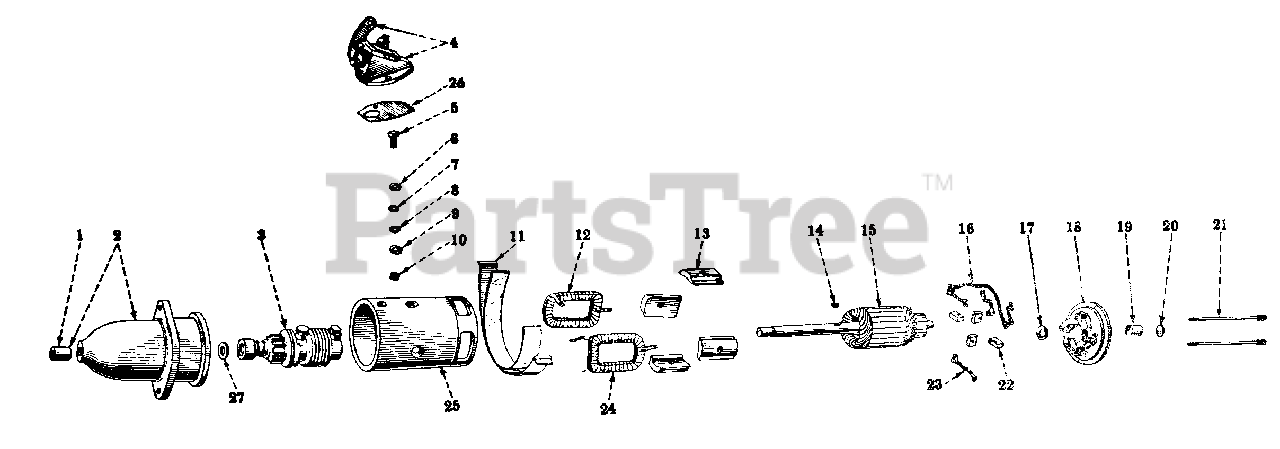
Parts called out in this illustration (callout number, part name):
1	BUSHING, DRIVE HOUSING
2	HOUSING W/BUSHING, 1839345, DRIVE
3	DRIVE ASSY. MOTOR
4	SWITCH ASSY. STARTING
5	STUD, TERMINAL
6	WASHER, TERMINAL STUD INSULATING
7	WASHER, TERMINAL STUD INSULATING
8	WASHER, TERMINAL STUD INSULATING
9	WASHER, TERMINAL STUD INSULATING
10	NUT, TERMINAL STUD
11	BAND, COVER
12	COIL, FIELD LH - UNIT A
12	COIL, FIELD LH - UNIT B
14	KEY, 5/32 X 5/8 WOODRUFF NO 6 ALY-STL
16	LEAD, BRUSH TO FIELD COIL
17	WASHER, COMMUTATOR END SPACE
18	FRAME ASSY, COMMUTATOR END
19	BUSHING, COMMUTATOR END FRAME
20	PLUG, COMMUTATOR END FRAME
23	LEAD, GROUND BRUSH
24	COIL, FIELD RH - UNIT A
24	COIL, FIELD RH - UNIT B
25	FRAME
26	GASKET, STARTING SWITCH
27	WASHER, DRIVE END SPACE
